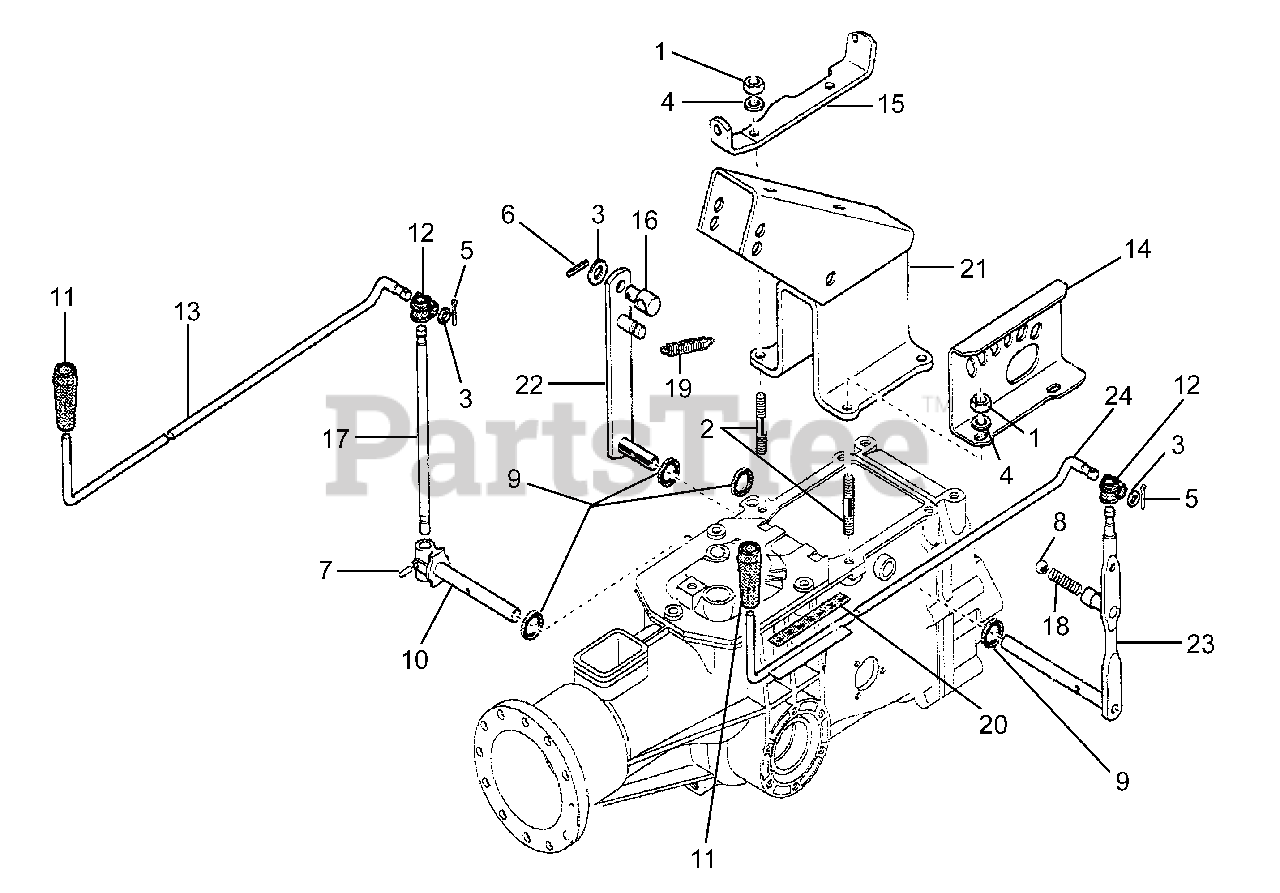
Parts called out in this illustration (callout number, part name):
1	LOCKING NUT M8 DEFORM.6S
2	STUD M8X38X14X20
3	FLAT WASHER10.5X18 UNI6592AC.
4	SUPER WASHER 8 DIN6796 GALV.
5	COTTER PIN 3X15 UNI 1336 ACC.
6	SPRING SPIGOT 3X16DIN1481 ACC
7	SPLIT PIN 4X20 SPIROL
8	BALL 15/32 RIV RB 11.906
9	OIL SEAL 14X22X4
12	SWIVEL D 10
13	CONTROL ROD
14	GEAR SELECTOR MF
15	REVERSE ROD LEVER EXTENSION
16	SHEATH STOP
17	PTO LEVER FOR MF
20	DECAL/SHIFTER
21	2-WH.TRACT.STEERING COL.SUPP.
22	INVERTER LEVER COMPL.
23	GEAR LEVER COMPL. FOR MF
24	GEAR STICK MF
